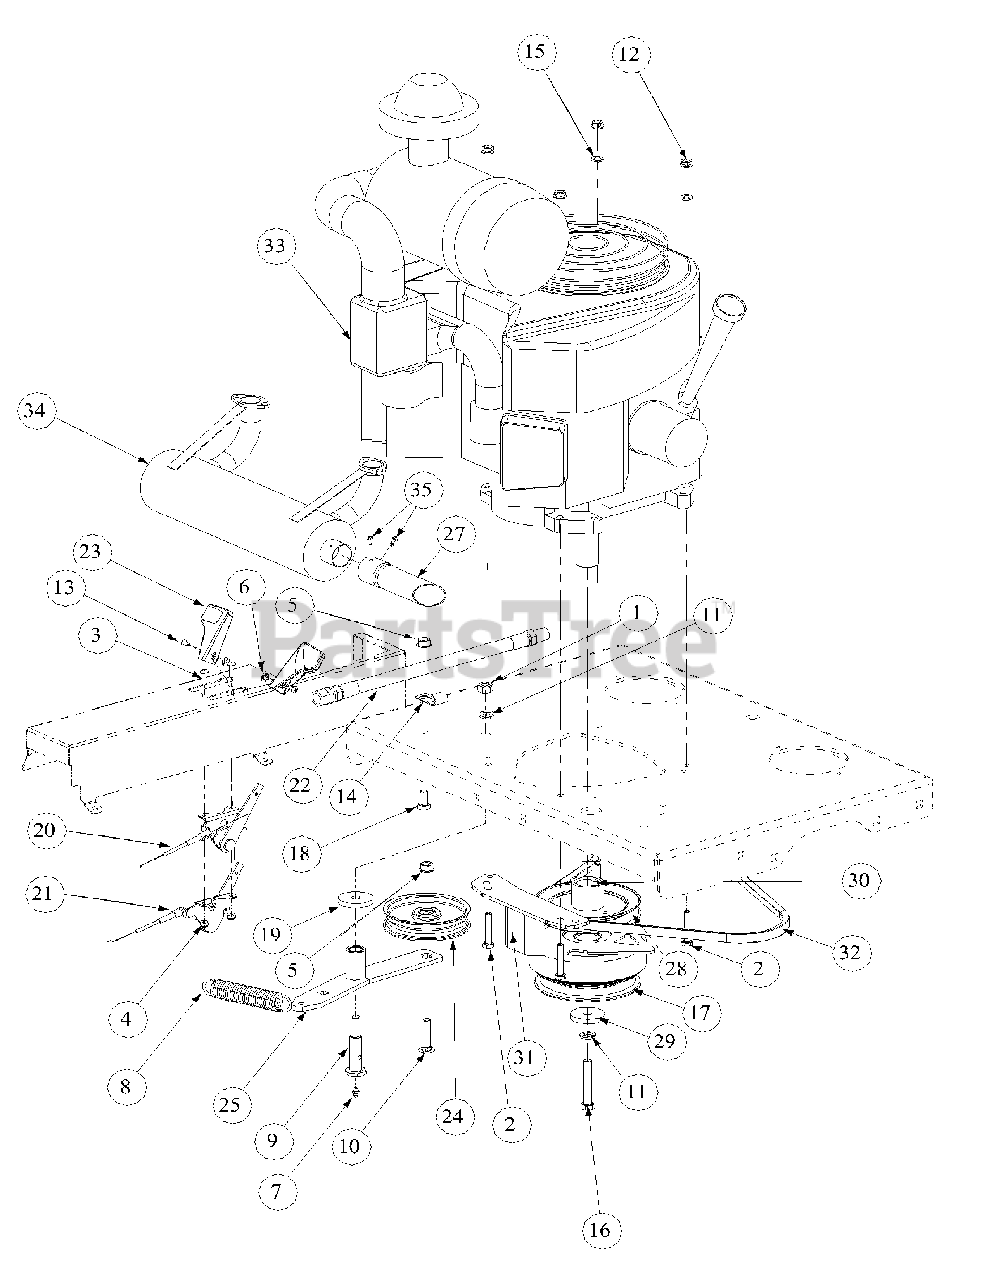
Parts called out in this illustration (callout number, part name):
1	Hex Nut, 7/16-14
2	HHCS, 5/16-18, 1-3/4
3	Round Hd. Machine Screw, 10-32 x 3/4
4	Lock Nut, Nylon Insert, 10-32
5	Flange Lock, Hex Nut, 3/8-16
6	Nut Washer, W/Star, 8-32
7	Grease Fitting, 1/4-28 x 3/16
8	Extension Spring, 1.0 OD x 5.00
9	Shoulder Screw, 7/16-14
10	Hex Carriage Screw, 3/8-16, 1.75
11	Lock Washer, 7/16
12	Hexflange Lock Nut, 5/16-18
13	Machine Screw, 8-32, .375
14	Clip, Heat Shield Cable
15	Flat Washer, 5/16
16	Capscrew, 7/16-20 x 2.50
17	Clutch Brake, 1.125 ID, 5.34 inch pulley
18	Hex Cap Screw, 3/8-16, .750
19	Flat Washer, 7/16 ID x 1.75 OD x .25
20	Choke Control Cable
21	Throttle Control Cable
22	Oil Drain Hose
23	Control Throttle Knob
24	Flat Pulley with Flanges
25	Engine Idler Arm Assembly includes:
27	Muffler Accessory Exhaust Tube
28	Pump Drive Pulley 28HP
28	Pump Drive Pulley 33HP
29	Flat Washer, 7/16 ID x 1.75 OD x .25
30	Key, 1/4 x 1/4 x 2.75 OR
30	Key, 1/4 x 1/4 x 1.125
31	Retainer Clutch Assembly, Ogura
32	Belt, 51.2 Lg
33	Engine, 28HP Generac
33	Engine, 33HP Generac
35	Screw, #8-32 x .375
